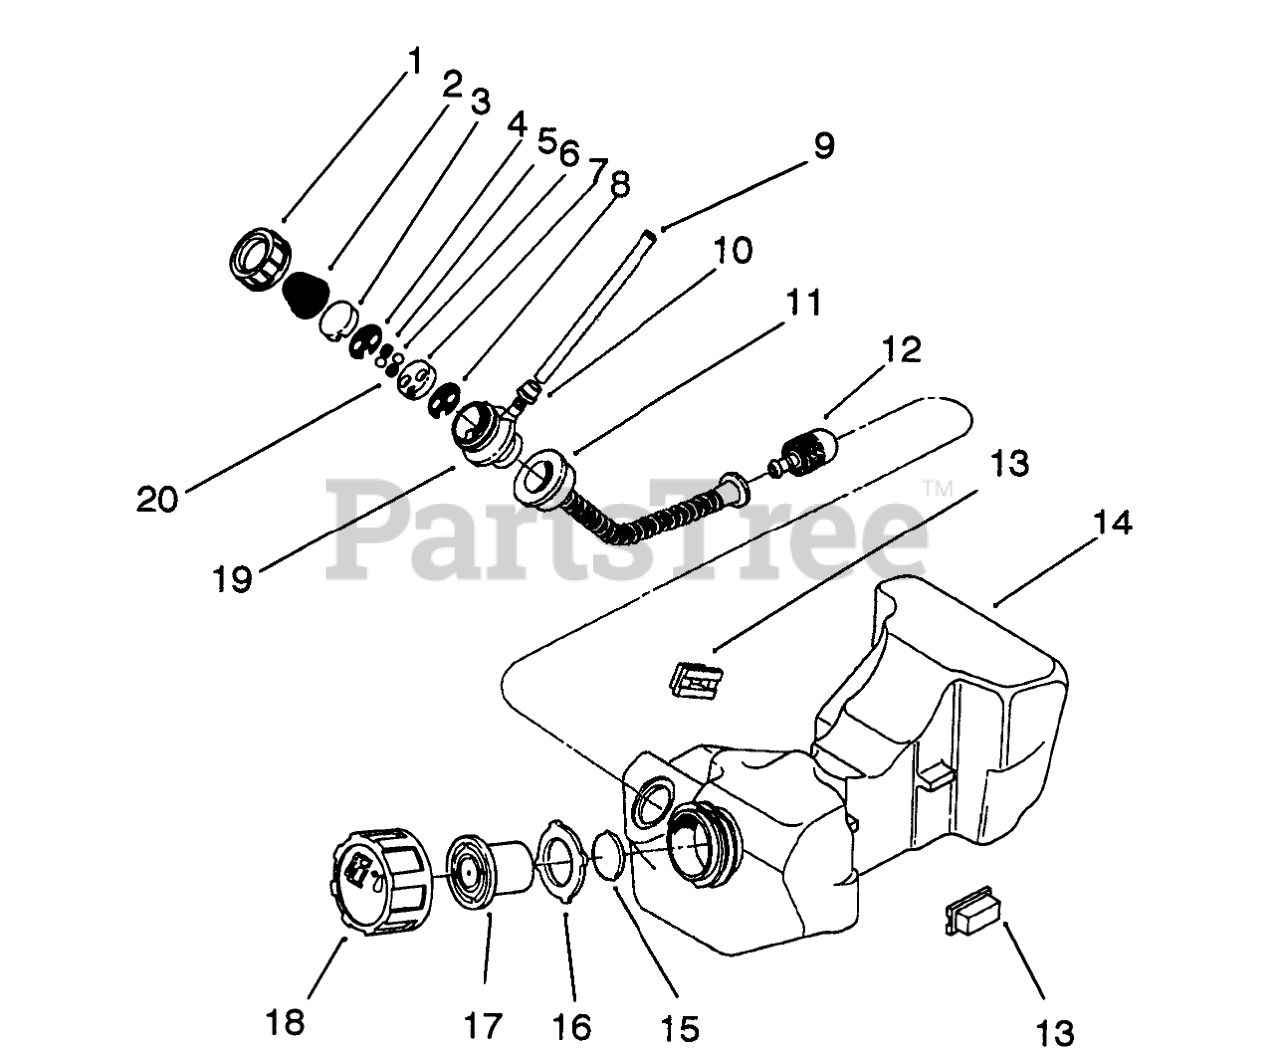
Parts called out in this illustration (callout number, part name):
1	PUMP CAP
3	SEAT VALVE
4	GASKET
5	SPONGE
7	SEAT VALVE
8	GASKET
9	Tube-Fuel
11	SUCTION HOSE
12	FUEL FILTER
14	Fuel Tank Assembly (Incl. Ref. #11, 12, 15-18 & 19)
16	PACKING
17	BREATHER VALVE
18	FUEL TANK CAP
19	Pump Priming Assembly (Incl. Ref. # 1-8 & 20)
20	Cushion Ball
